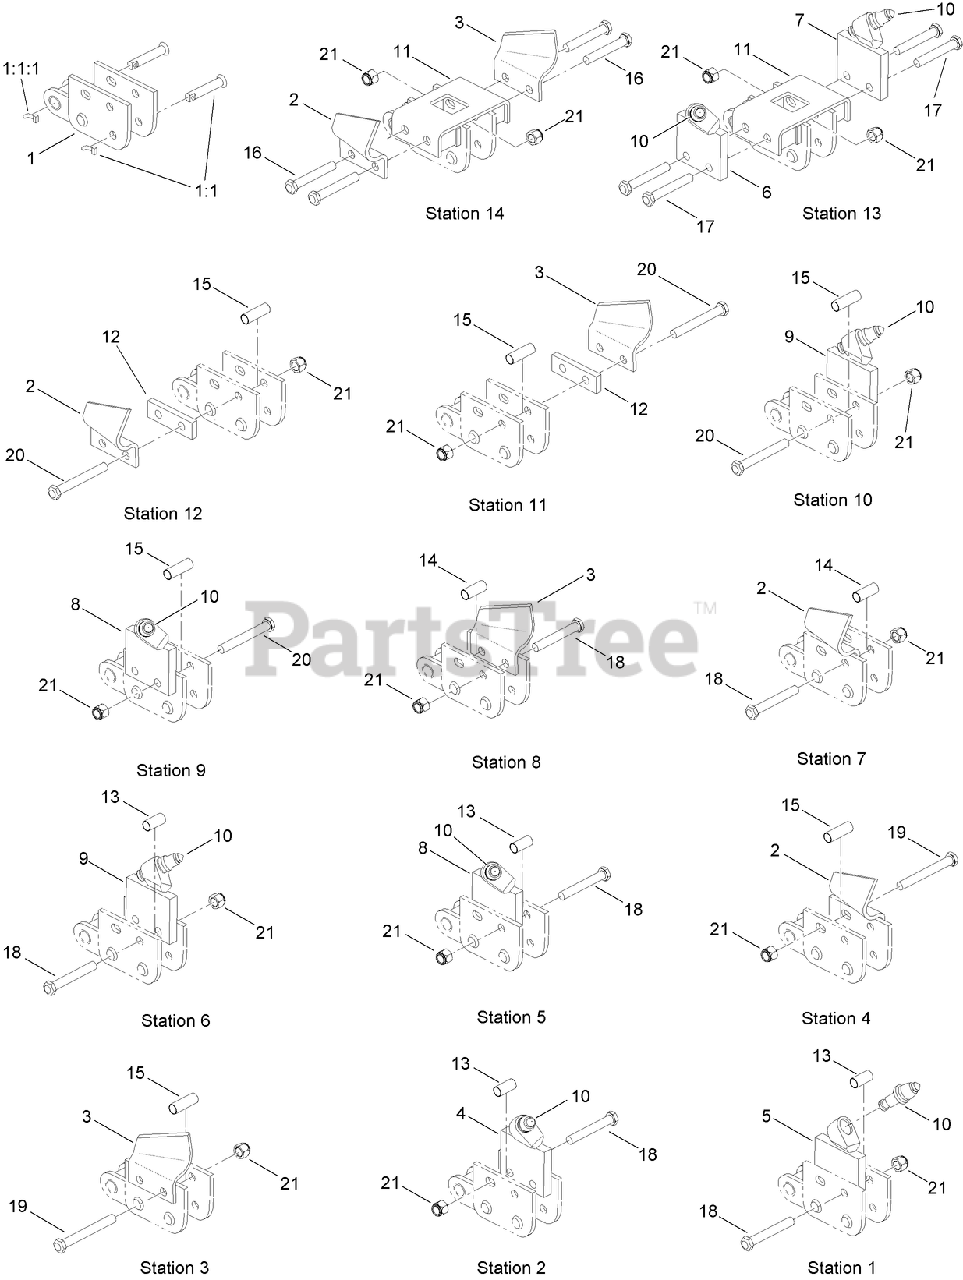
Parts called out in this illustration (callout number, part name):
1	CHAIN REPAIR LINK ASM
1:1	NOTCHED PIN AND KEEPER ASM
1:1:1	PIN-KEEPER
2	CUTTER-CUP, RH
3	CUTTER-CUP, LH
4	HOLDER-BIT, RH CENTER
5	HOLDER-BIT, LH CENTER
6	HOLDER-BIT, RH
7	HOLDER-BIT, LH
8	HOLDER-BIT, RH
9	HOLDER-BIT, LH
10	BIT-CARBIDE, FULL CAB
11	SADDLE-TOOTH SPREADER
12	SPACER-FLAT
13	SPACER-TUBE, INSIDE ADAPTER
14	SPACER-TUBE, INSIDE CUP
15	SPACER-TUBE, OUTSIDE MOUNT
16	BOLT-HH
17	BOLT-HH
18	BOLT-HH
19	BOLT-HH
20	BOLT-HH
21	NUT-LOCK
